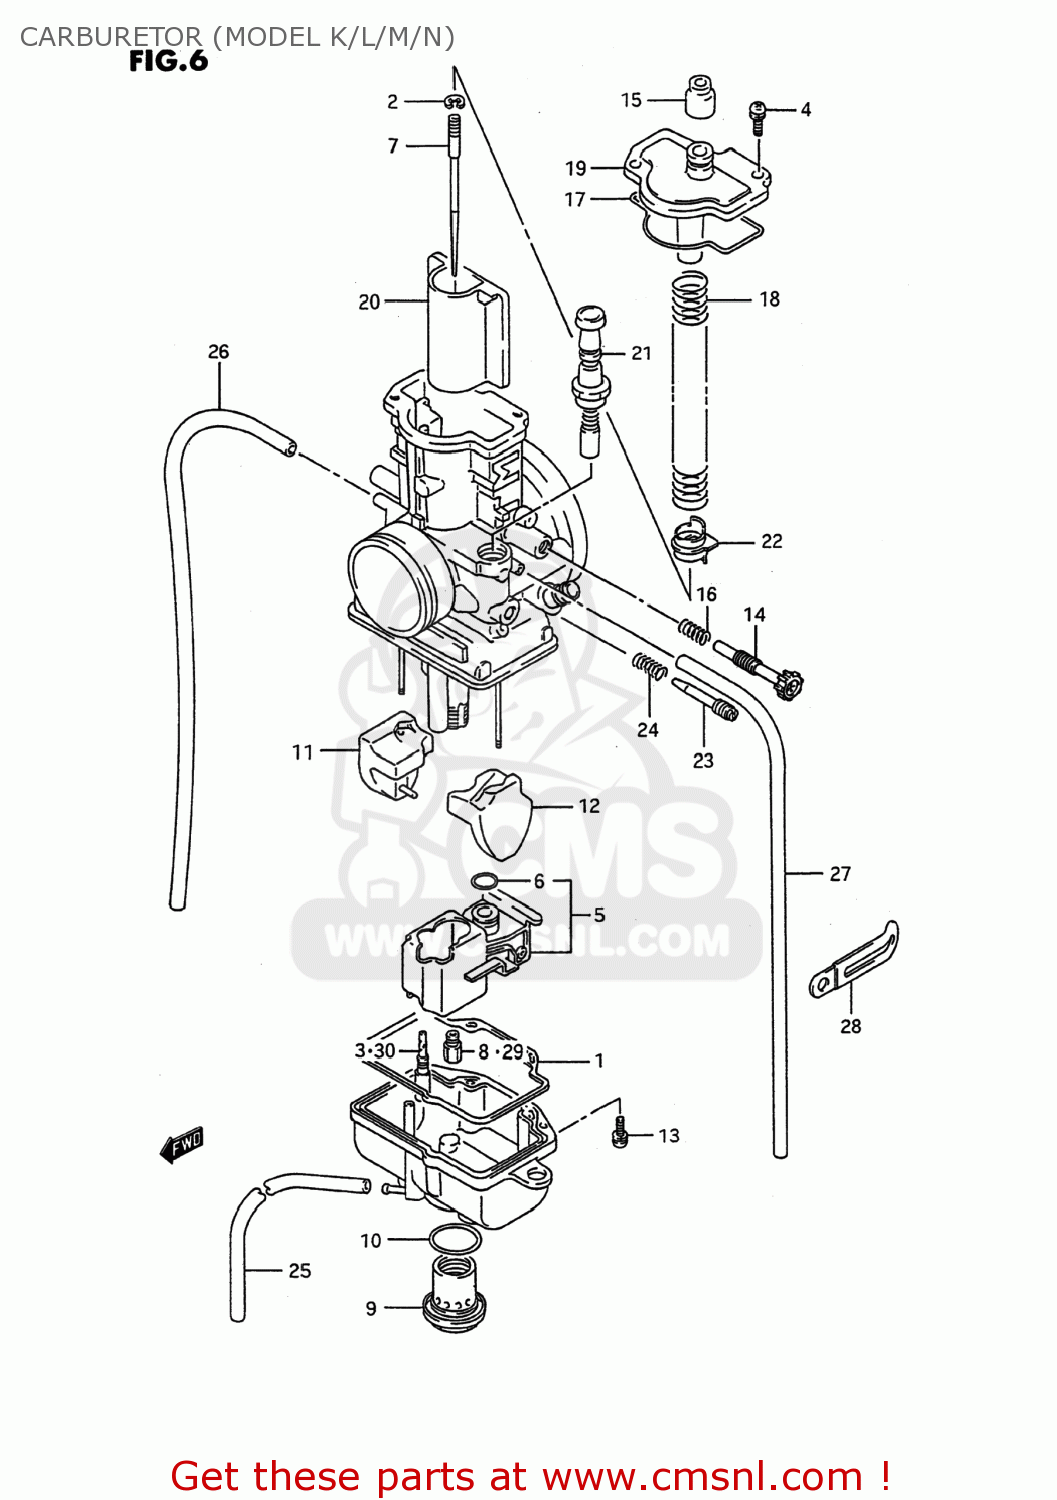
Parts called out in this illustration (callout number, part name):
1	O RING,FLOAT CHAMBER
2	CLIP,NEEDLE
3	JET,PILOT(45)
4	SCREW
5	VALVE ASSY,NEEDLE
6	O-RING,NEEDLE VALVE
7	NEEDLE,JET
8	JET
9	CAP,DRAIN
10	O RING
11	FLOAT,R
12	FLOAT,L
13	SCREW
14	ADJUSTER
15	CAP
16	SPRING
17	O RING,TOP CAP
18	SPRING
19	CAP,TOP
20	VALVE,PISTON(CA:3.5)
21	PLUNGER ASSY
22	RING
23	SCREW,AIR
24	SPRING
25	HOSE(3X5X600)
26	HOSE
27	HOSE
28	CLAMP
29	JET
30	JET,PILOT(50)
